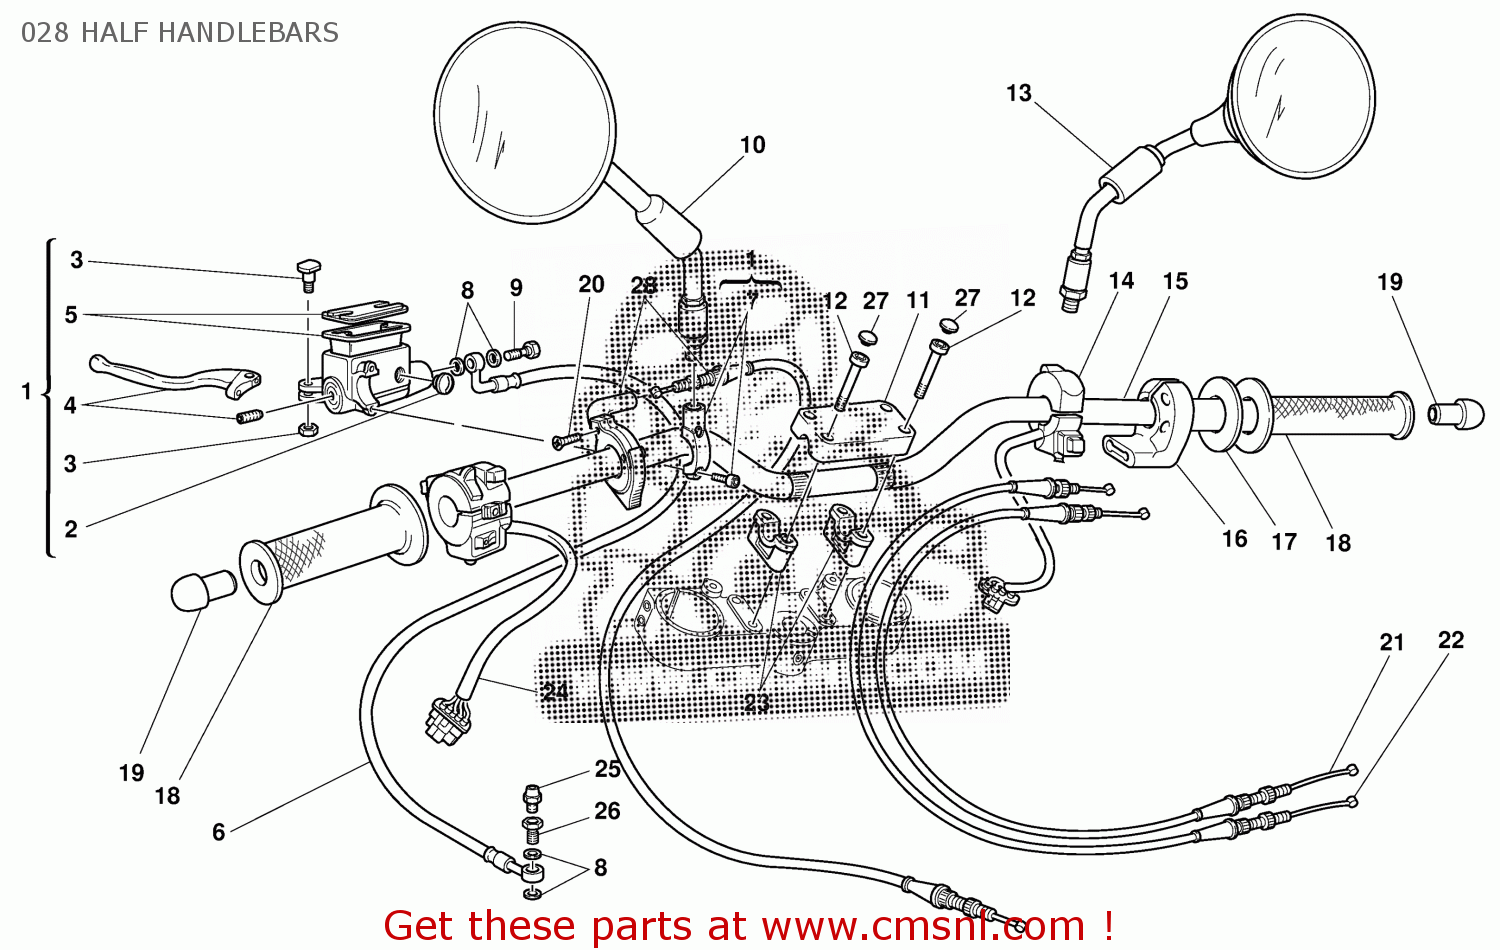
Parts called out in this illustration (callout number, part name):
1	CLUTCH PUMP
2	WINDOW, OIL LEVEL CHECK
3	BOLT, HANDLE LEVER PIVOT
4	LEVER
5	CAP, RESERVOIR
6	CLUTCH OIL HOSE
7	BRACKET, MASTER CYLINDER
8	COPPER GASKET 11.9X8.2X2
9	SCREW, SPECIAL
10	LEFT MIRROR
11	HANDLEBAR BRACKET, UPPER
12	SCREW
13	RIGHT MIRROR
14	RIGHT HANDLE SWITCH
15	HANDLEBAR
16	THROTTLE CONTROL
17	WASHER
18	GRIPS, PAIR
19	BALANCER SET, HANDLE BAR
20	SCREW
21	THROTTLE CLOSING CABLE
22	THROTTLE OPENING CABLE
23	HANDLEBAR BRACKET, LOWER
24	LEFT HANDLE SWITCH
25	VALVE, BREATHER
26	BOLT, BRAKE HOSE
27	PLUG
28	STARTER CONTROL TRANSMISSION
